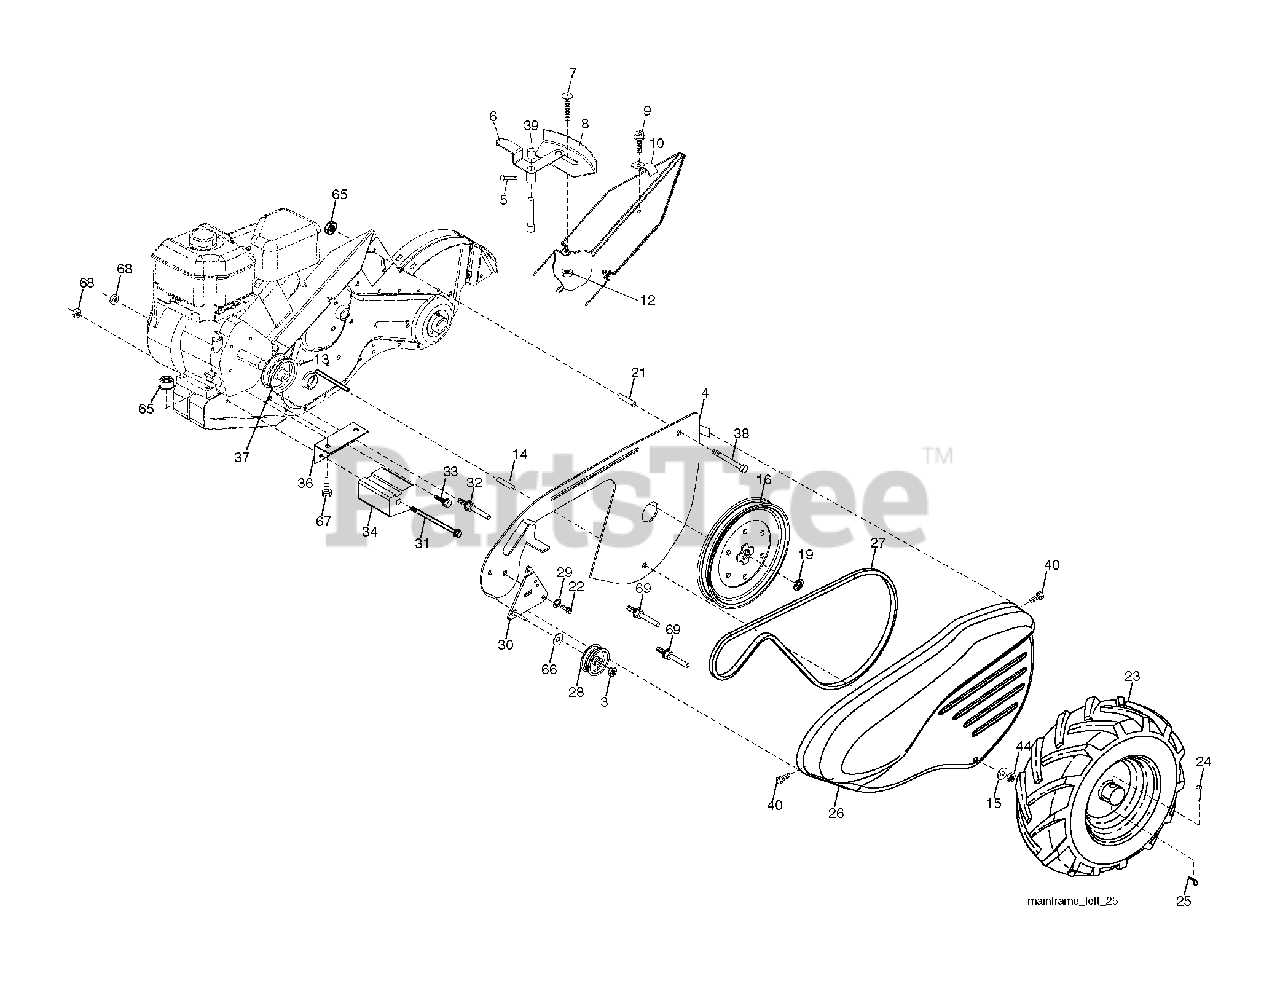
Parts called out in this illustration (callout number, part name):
3	NUT.HEX.3/8-16UNC
4	SHIELD.INNER.BELT.GUARD.RT
5	PIN.SPIROL.FLARED
6	LEVER ASM CRT
8	PANEL.INDICATOR.SHIFT.BLACK
10	CONDUIT CLIP T
12	NUT
13	SET SCREW
14	SPACER-SPLIT.327 X .42
15	WASHER
16	SHEAVE, TRANSMISSION
19	RETAINING RING LT
21	SPACER CRT
23	TIRE.16X4-8.CHEVRON.TILLER
24	RIVET,DRILLED
26	BELT GUARD
27	V-BELT
28	PULLEY-IDLER TI
29	KLIP RING
30	BRACKET.ASM.IDLER.BLACK
31	BOLT.FIN.HEX.3/8-16UNC
32	SHIFT ARM CRT
33	BOLT
34	COUNTERWEIGHT.LH.CRT
36	BRACKET LH CRT
37	V-BELT
39	CAP.PLUNGER.BLACK
40	SCREW.HEX.WSH.SLT.#10-24X.50
44	NUT.71038.31-18.HEX.NYLOCK
65	LOCKNUT-FLANGE 5/16-18
66	WASHER
67	BOLT
69	KEEPER.BELT.ENGINE
